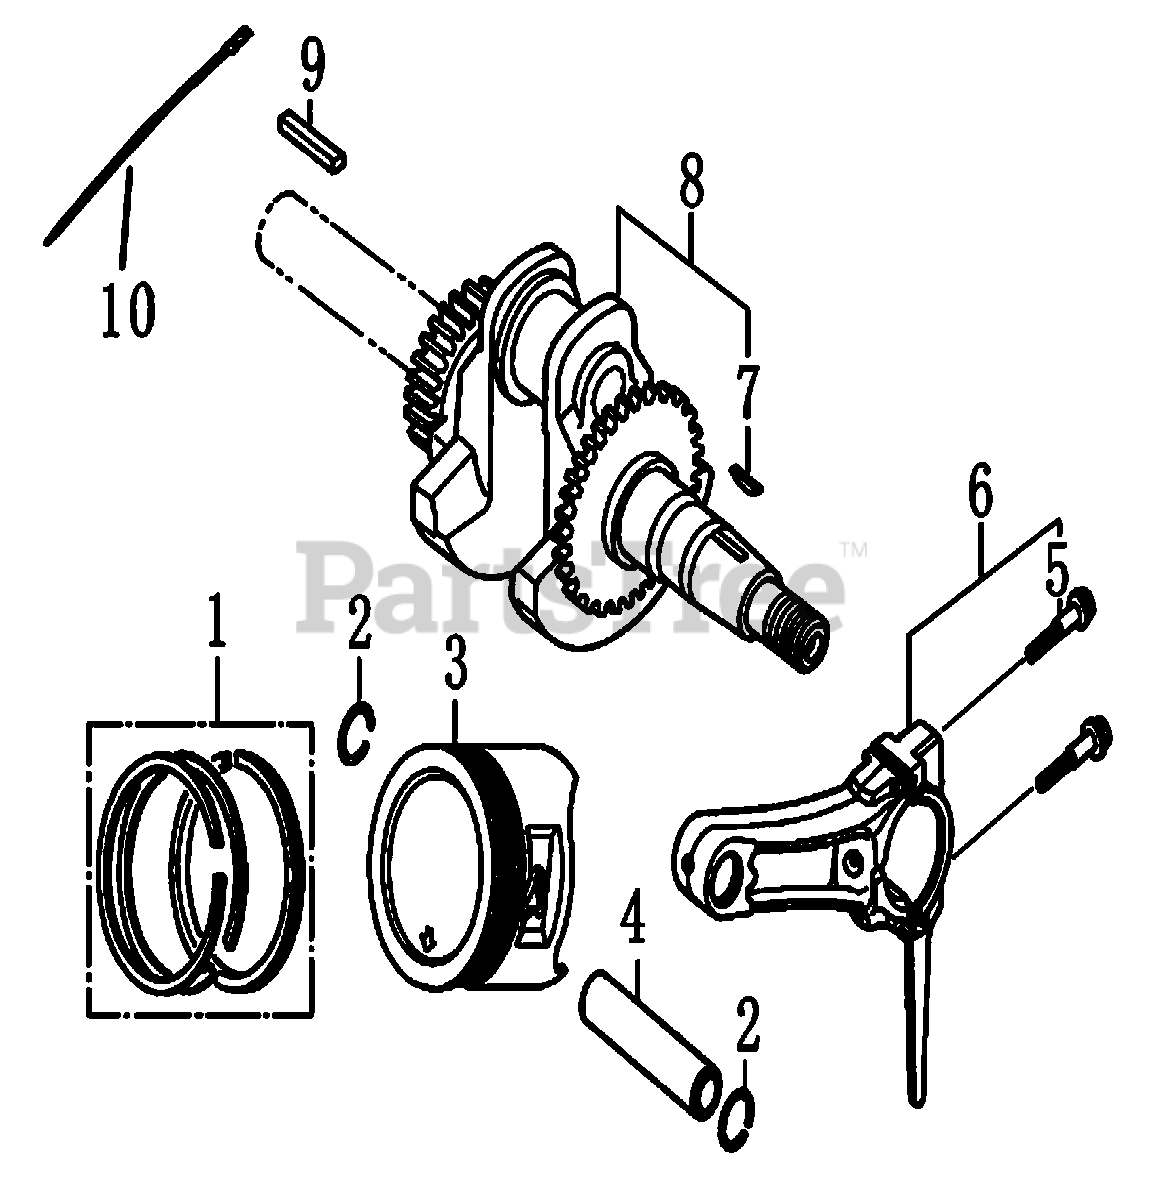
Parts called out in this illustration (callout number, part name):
2	CLIP, PISTON PIN
4	PIN, PISTON
5	BOLT, CONNECTING ROD
6	ROD ASSY, CONNECTING
8	CRANKSHAFT COMP
10	TIE WRAP UL 7.4"X .19" BLK
